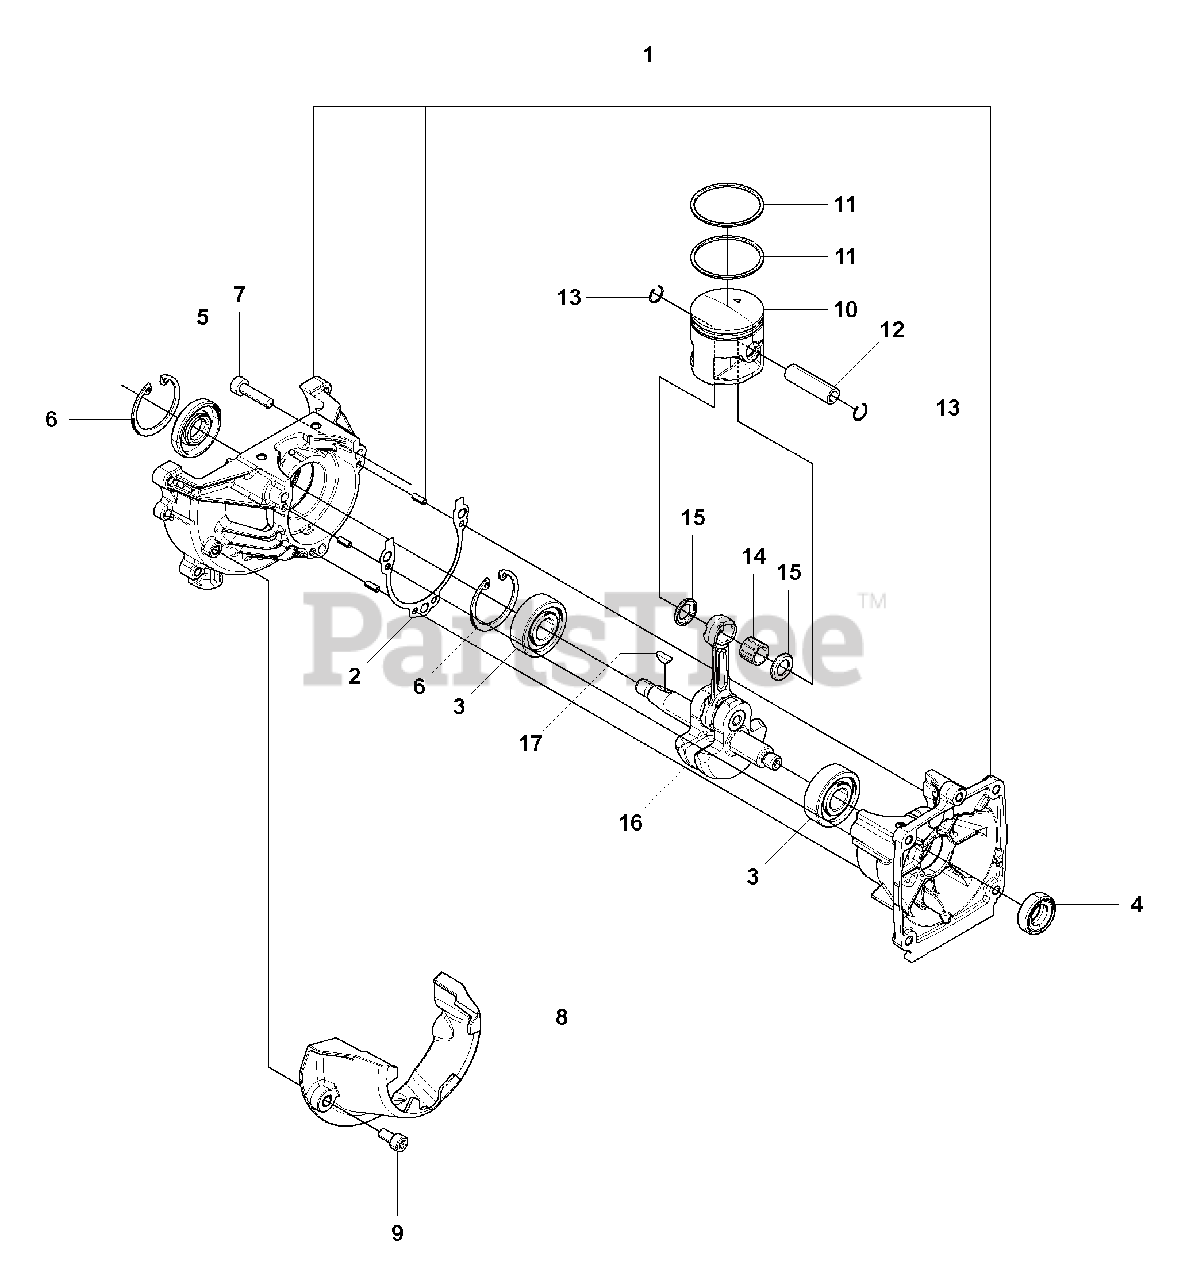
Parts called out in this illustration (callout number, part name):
1	CRANKCASE-C
2	GASKET CASE
5	SEAL
7	BOLT
8	Case Cover
9	BOLT 08
10	PISTON
16	CRANKSHAFT C
17	KEY
